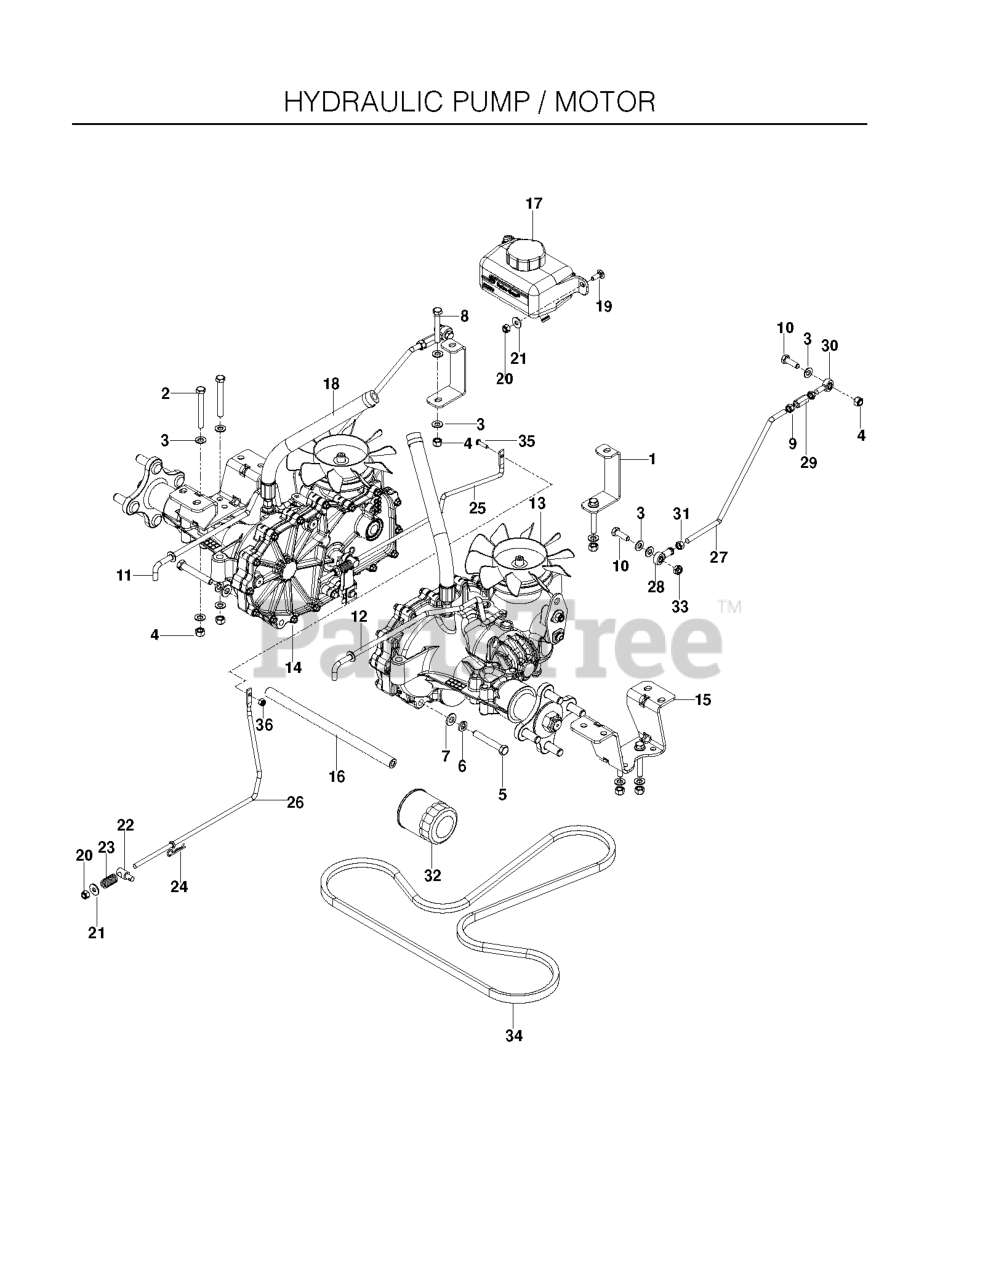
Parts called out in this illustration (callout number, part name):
1	SUPPORT.FRONT.TRANS.BLACK.
2	HCS 5/16C X 2-3/4
3	FLAT WASHER 5/16 SAE
4	NUT 5/16 NYLOC
5	HCS 3/8C X 2 1/2
6	SLW 3/8 STD
7	WASHER 3/8 SAE FLAT
9	NUT 5/16F LEFTHAND
10	HCS 5/16C X 1
11	ROD, BYPASS, RT
12	ROD, BYPASS, LT
13	HG_TRANS, ZT-2800 RT
14	HG_TRANS, ZT-2800 LEFT
15	EZT MOUNT, REAR, BLACK
16	SPACER TUBE, EZT, 11.08
17	HG_EXPANSION TANK W/CAP 71354
19	RHSNB 1/4C X 3/4
20	NUT.1/4-20.HEX.NYLOC.ZD
21	WASHER 1/4 FLAT
22	BRAKE SWIVEL
24	HAIRPIN #2
25	LINKAGE.BRAKE.LT
26	LINKAGE, BRAKE RT
27	ROD, MOTION CONTROL
28	RH ROD END
29	ROD END COUPLER
30	RP.ROD.END.LH
32	HG_FILTER, ZT4800 52114
33	5/16-18 THIN PROF NY
34	BELT, EZT HYDRO
35	SCR #10-24 X 3/4
36	NUT 10-24 NYLOC
